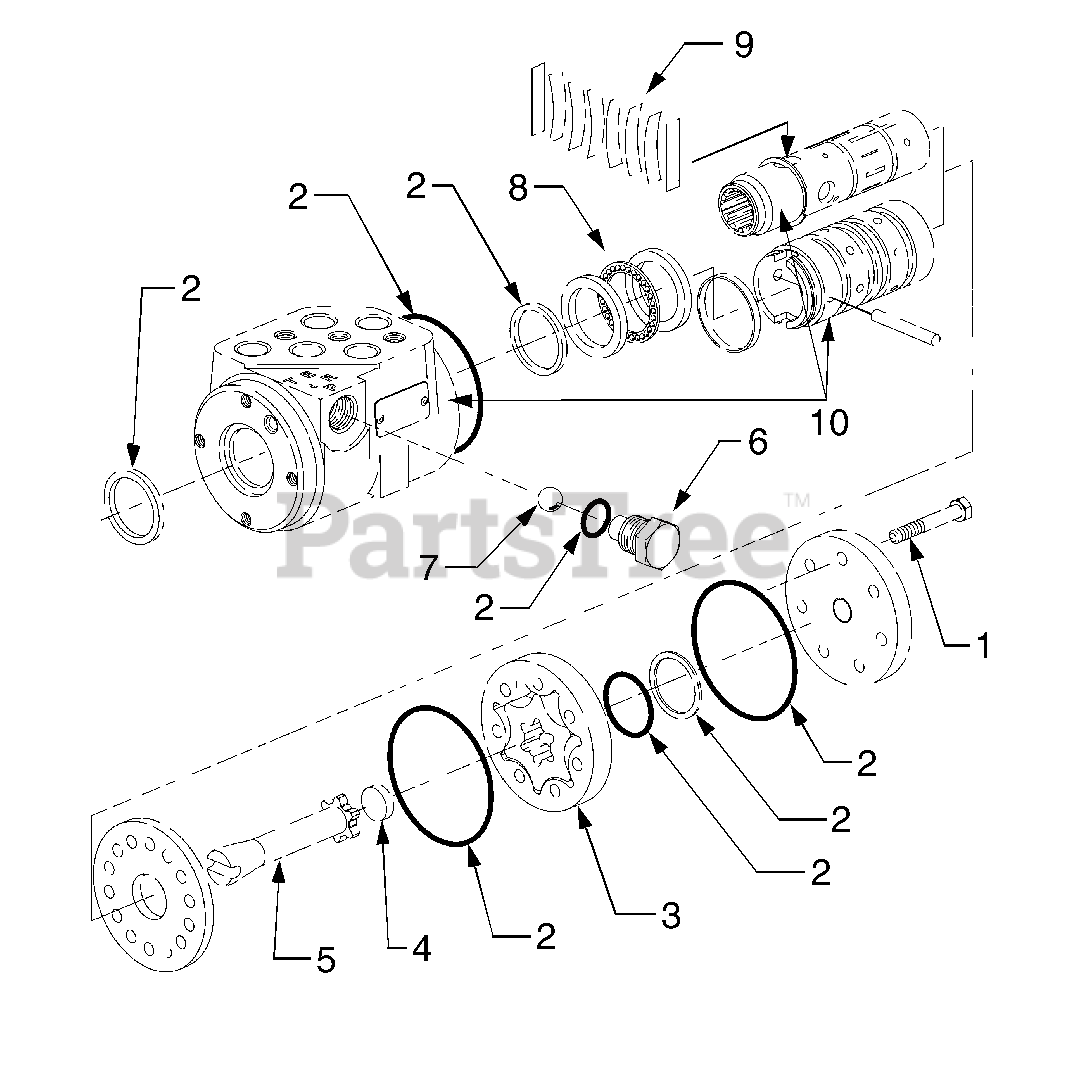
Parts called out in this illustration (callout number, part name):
1	Screw, Hex Cap, 1.57" Lg.
2	Seal Kit
3	Gerotor Assembly
4	Spacer, .240 Lg.
6	Plug, Manual Check
7	Ball, Manual Check
9	Spring Kit, Centering
10	Spool, Sleeve and Housing
